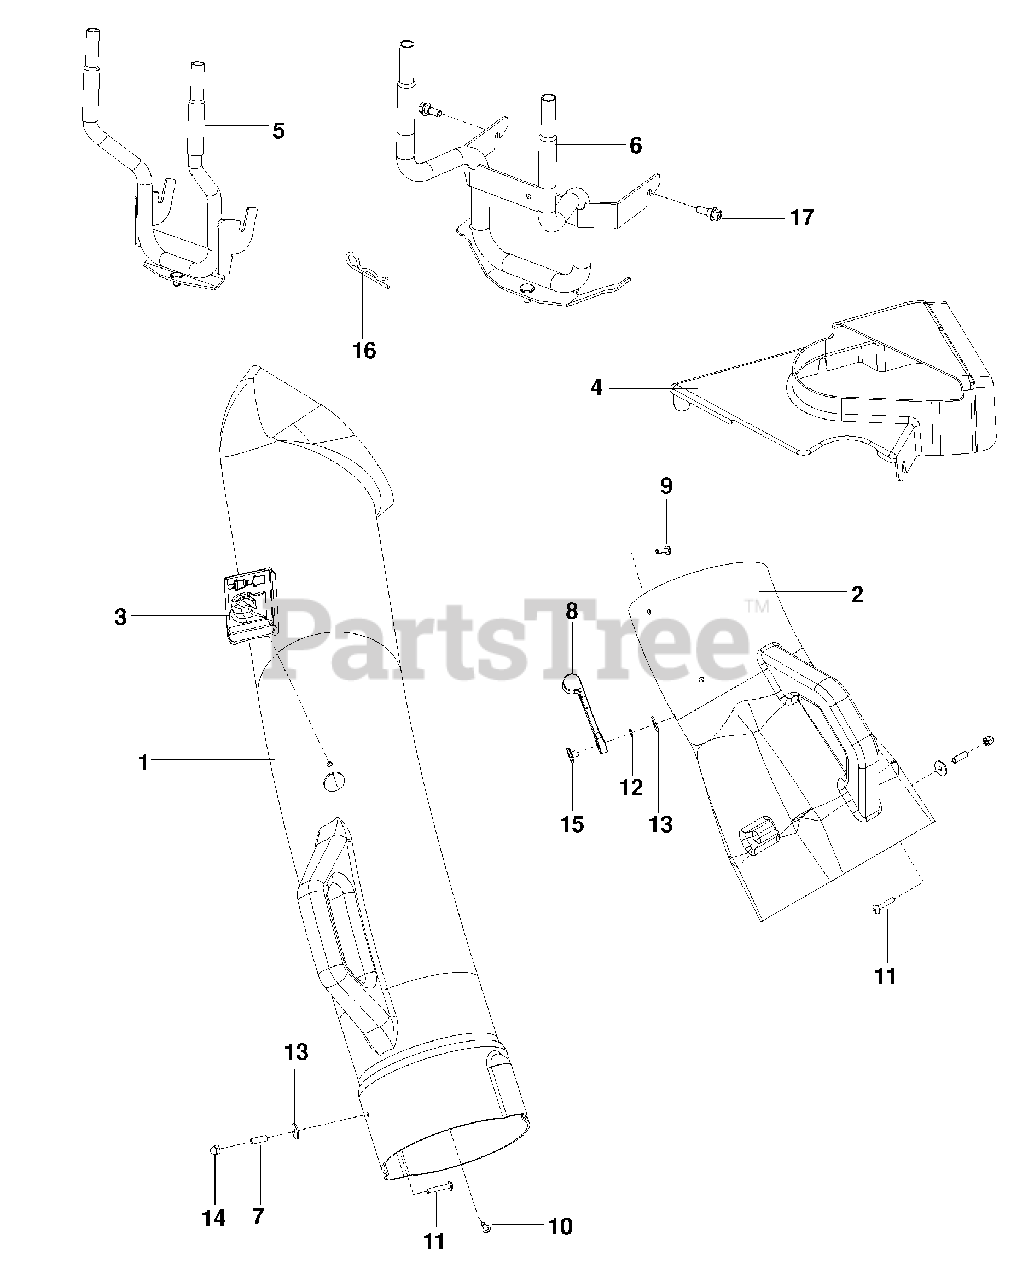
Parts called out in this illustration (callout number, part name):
1	CHUTE, UPPER
2	CHUTE, MIDDLE
3	INDICATOR, BAG DUMP
4	SHIELD, BELT
5	SUPPORT TUBE ASSY
6	SUPPORT TUBE ASSY
7	SPACER, SPLIT
8	LATCH, CHUTE
9	SCREW 10-24 x .625 MACH
10	SCREW, SPEC 10-14 x 1/2
11	SCREW 10-24 x 11/8
12	WASHER 3/16 LOCK
13	WASHER 3/16 x 3/4
14	NUT, ACORN 10-24
15	WELD NUT, PLATED
17	BOLT 3/8-16 SHOULDER
